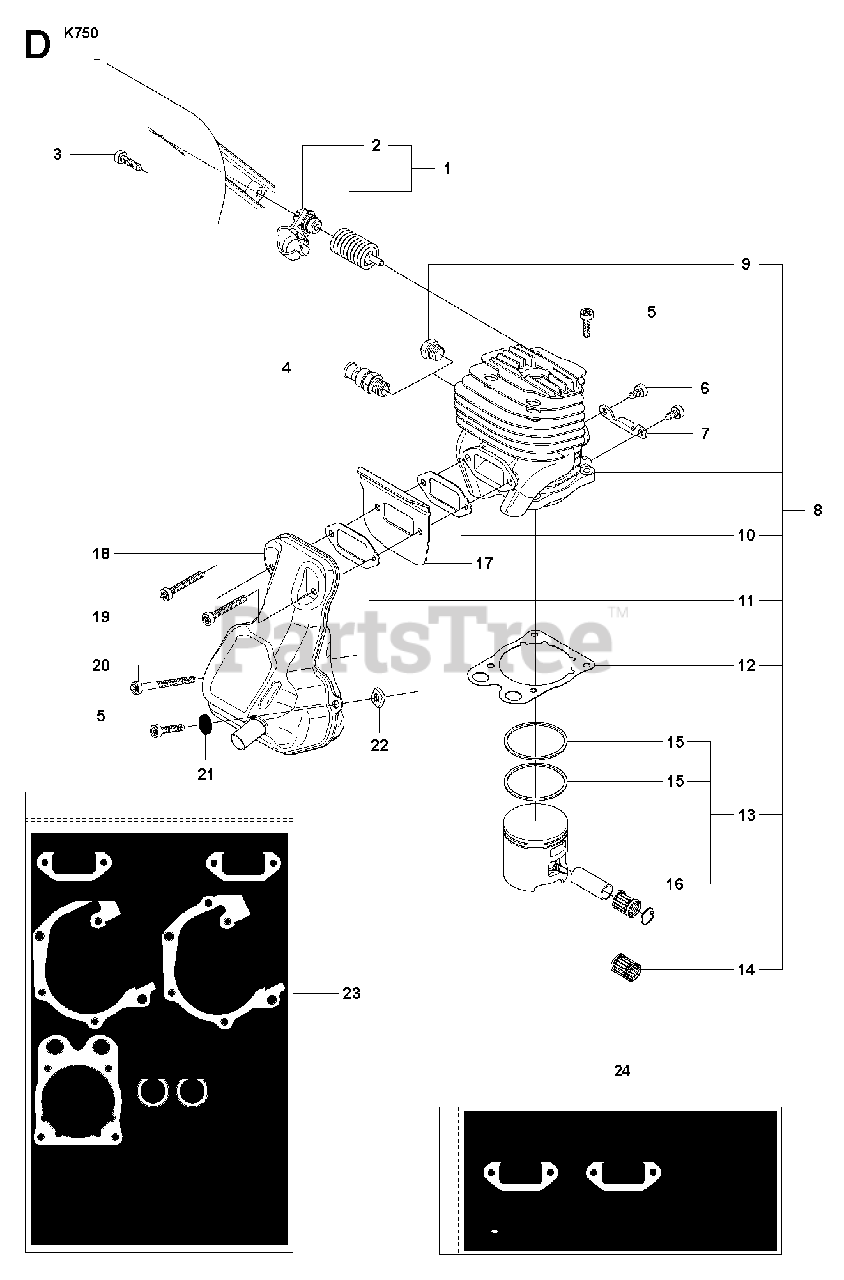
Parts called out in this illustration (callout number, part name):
1	ANTIVIBRATION ELEMENTIncl. 2
2	SPRING HOLDER
3	SCREW ITXSCM
4	DECOMPRESSION VALVE
5	SCREW ITXSCM
6	SCREW ITXSCM
8	CYLINDER ASSYIncl. 9 - 14
11	GASKET
13	PISTON ASSYIncl. 15 - 16
14	NEEDLE BEARING
15	PISTON RING
17	COOLING AIR CONDUCTOR
18	MUFFLER ASSY
19	SCREW ITXSCM
20	SCREW ITXSCM
23	GASKET KITIncl. 10 - 12, 25 - 29
24	MUFFLER KITIncl. 5, 10, 11, 19 - 22
28	SEALING RING
29	GASKET
